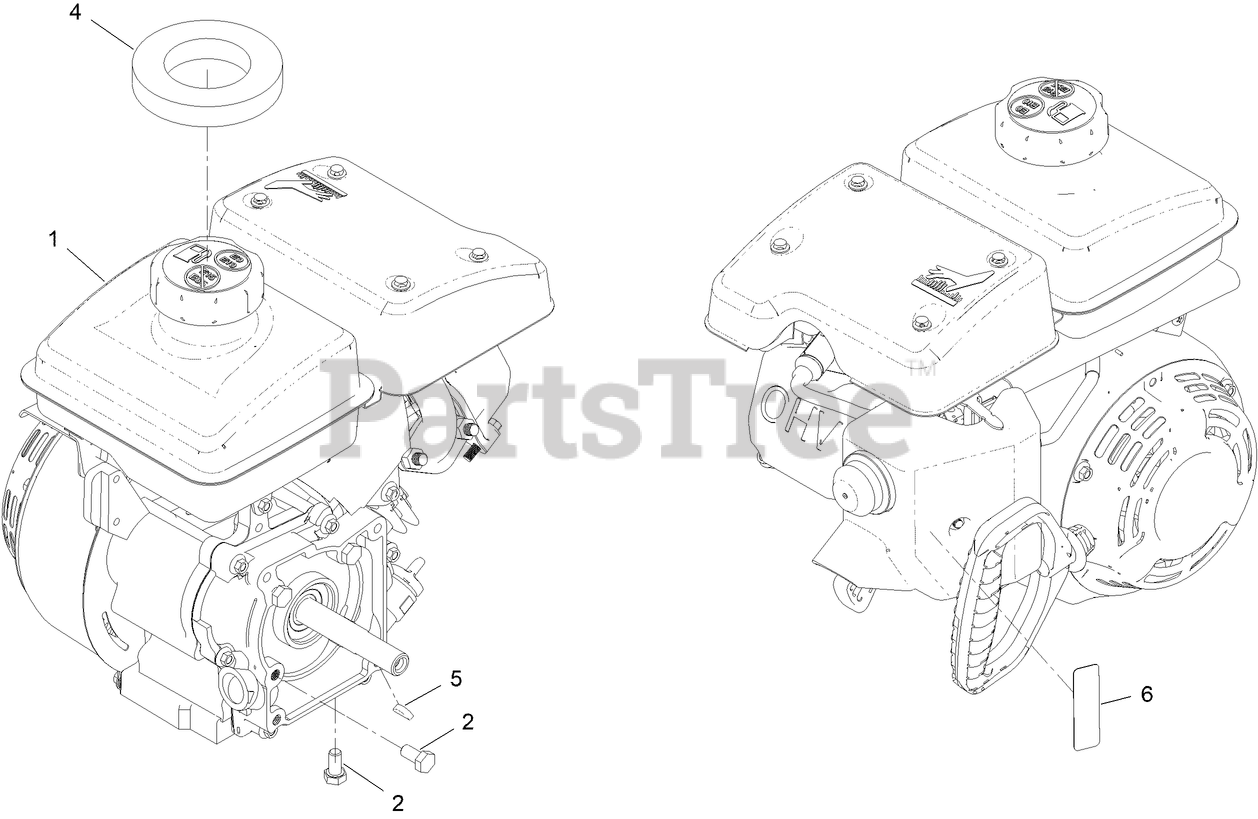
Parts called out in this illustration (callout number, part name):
1	ENGINE-LC156FS
2	SCREW-HH
4	SEAL-TANK
5	KEY-WOODRUFF
6	DECAL-CONTROLS, ENGINE
